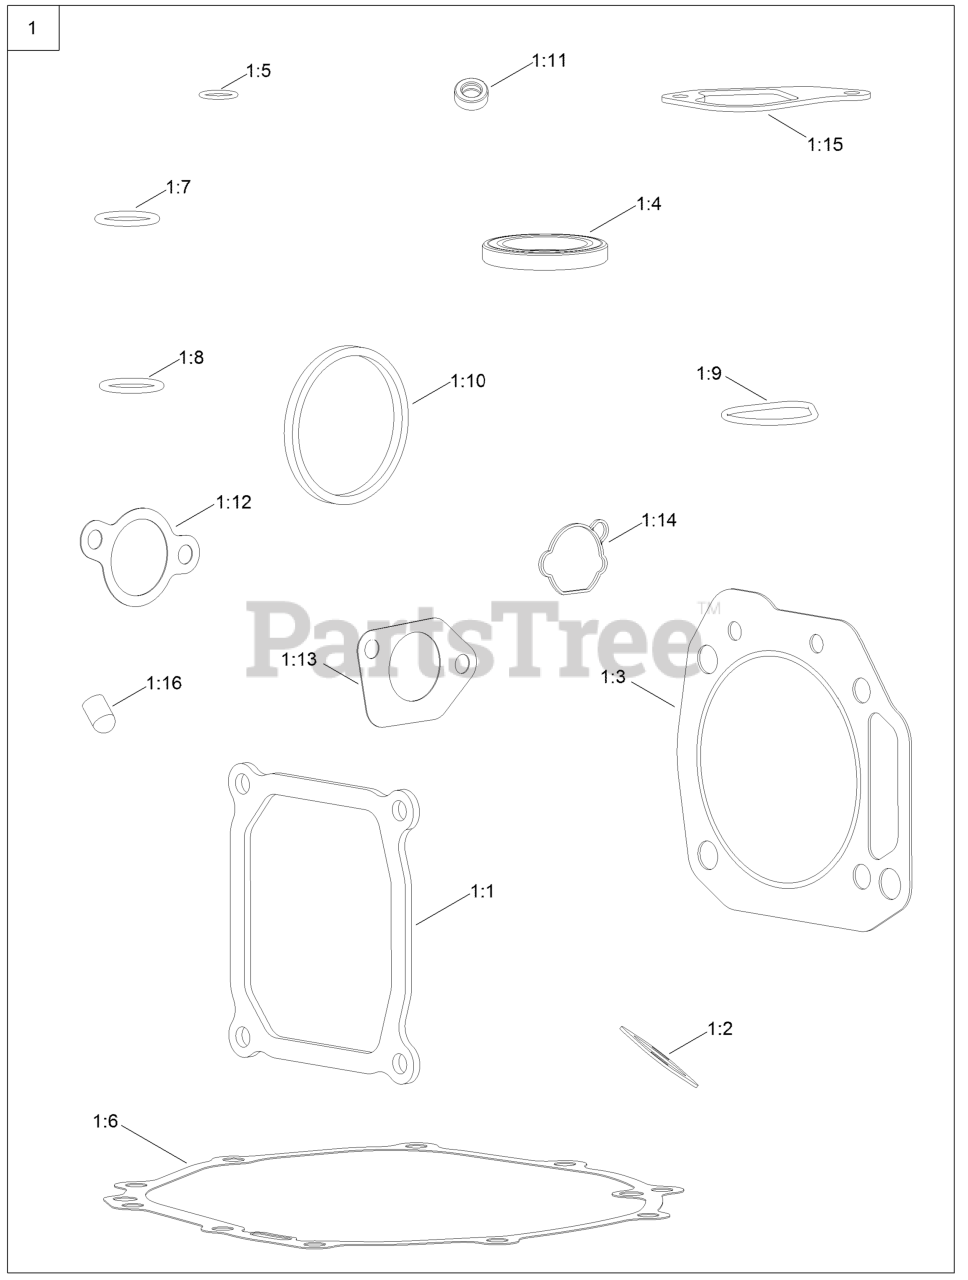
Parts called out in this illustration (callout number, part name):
1	GASKET AND SEAL KIT
1:1	GASKET-COVER, VALVE
1:2	GASKET-EXHAUST
1:3	GASKET-CYCLINDER
1:4	SEAL-OIL
1:6	GASKET-CRANKCASE
1:9	SEAL-PUMP, OIL
1:10	SEAL-ADAPTOR, OIL
1:11	SEAL-OIL
1:12	GASKET-CARBURETOR
1:13	GASKET-CARBURETOR
1:14	GASKET-CARBURETOR
1:15	GASKET-BREATHER
1:16	CAP-SEAL
